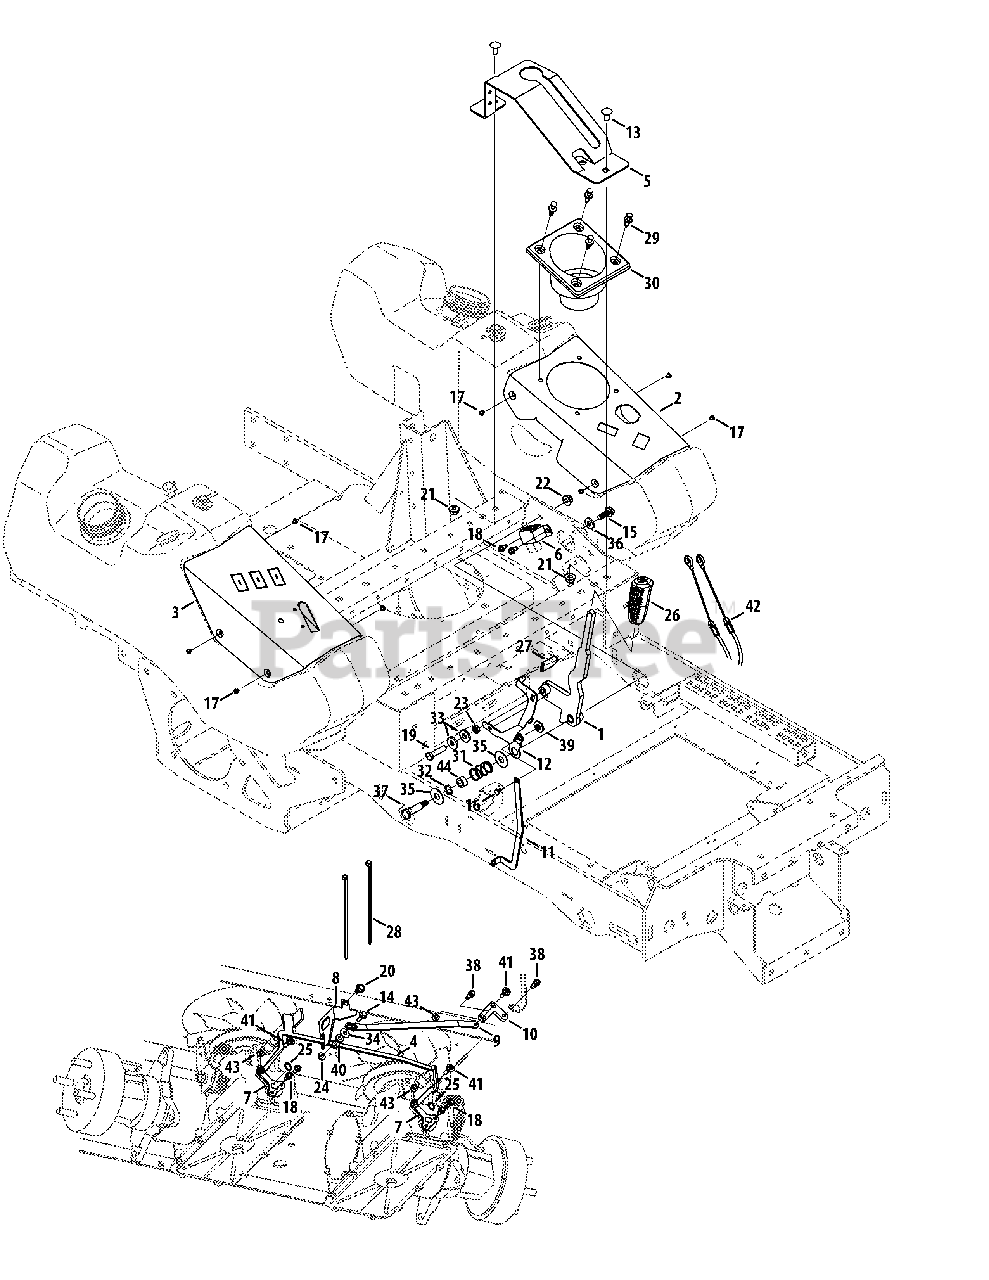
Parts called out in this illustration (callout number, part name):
1	Brake Handle Assembly
2	LH Control Panel
3	RH Control Panel
4	Dump Valve Actuator Bracket
5	Boot Brake Bracket
6	Brake Switch Mount
7	Transmission Bypass Lever
8	Neutral Switch Bracket
9	Transmission Actuator Arm
10	Neutral Pivot Control Lever
11	Neutral Arm
12	Dump Valve Release Lever
13	Carriage Bolt, 3/8-16 x .75
14	Hex Flange Screw, 1/4-20 x .75
15	Screw, 3/8-16 x 1.00
16	Screw, M6 x 8mm
17	Machine Screw, #10-32 x .25
18	Hex Flange Screw, 1/4-20 x .500
19	Hex Cap Screw, 3/8-16 x 1.50
20	Screw, 5/16-18 x .50
21	Nut, 3/8-16, Flangelock
22	Nut, 3/8-16, Flangelock
23	Jam Nut, 3/8-16
24	Nut, 1/4-20, Hexflange
25	Retainer Ring
26	Grip, .50 ID
27	Grip, Seat, Adjustment (Yellow)
28	Cable Tie
29	Rivet, .3125
30	Cup Holder
31	Compression Spring, .844 x .97 x 1.5
32	Washer, Wave, .531 x .781 x .013
33	Flat Washer, .385 x 1.00 x .135
34	Flat Washer, .283 x .750 x .030
35	Flat Washer, .508 x 1.325 x .040
36	Flat Washer, .406 x .875 x .105
37	Shoulder Screw, .498 x 1.445
38	Shoulder Screw, .342 x .335, 1/4-28
39	Shoulder Spacer, M6
40	Shoulder Spacer, .375 x .625 x .20
41	Shoulder Screw, .375 x .280, 1/4-14
42	Brake Cable
43	Spacer, .256 x .500 x .240
44	Spacer, .51 x .75 x .390
